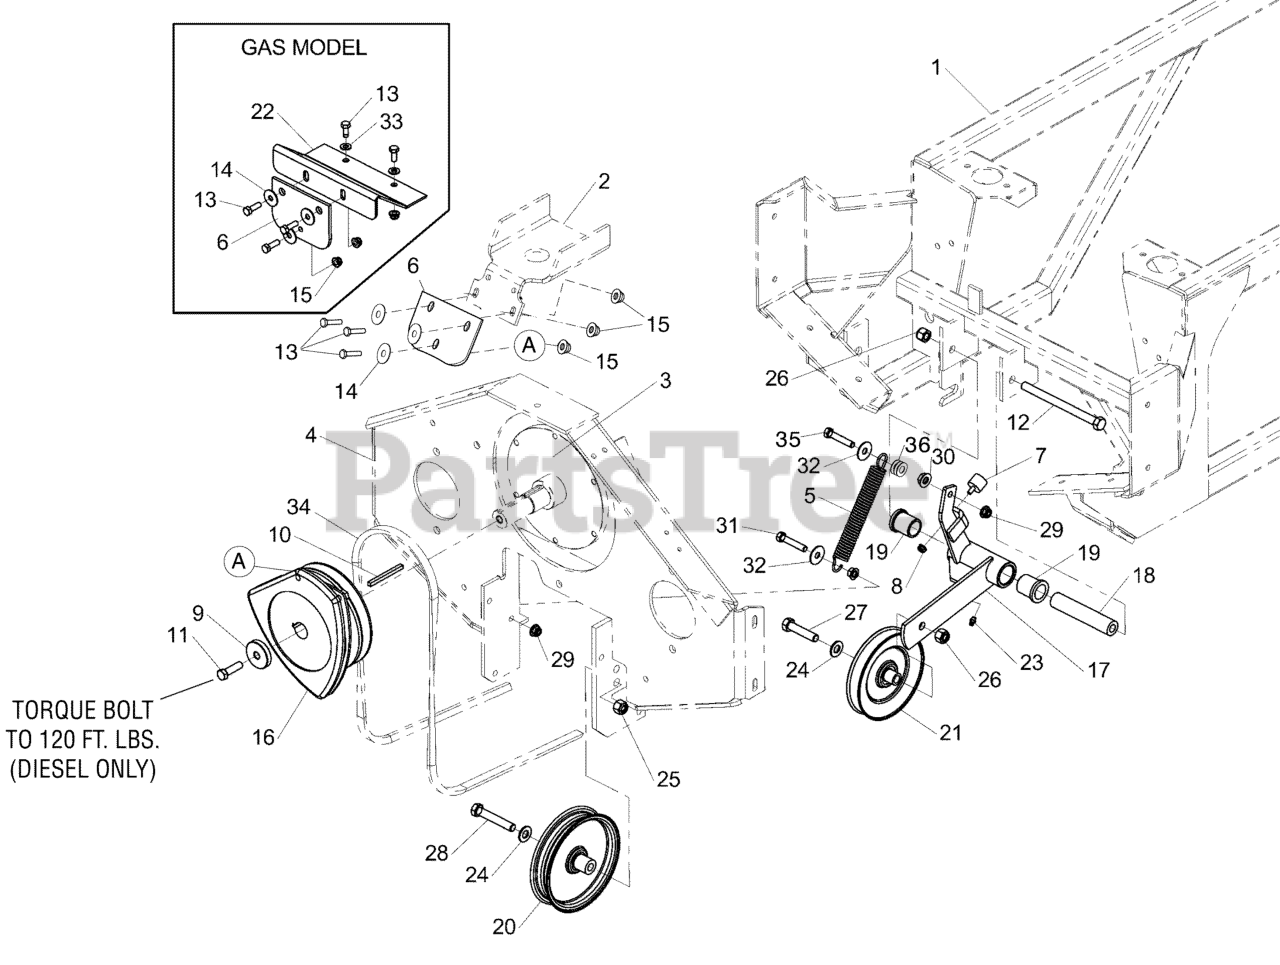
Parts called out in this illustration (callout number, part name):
1	MAIN FRAME
2	REAR ISO MOUNT
3	CRANK SHAFT / STUB SHAFT
4	PUMP PLATE
5	SPRING, EXTENSION, SWIVEL
6	CLUTCH ANCHOR PAD
7	RUBBER BUMPER 1/4-20
8	NUT, 1/4-20 HEX NYLON FLANGE
9	SPACER, .515 X 1.875 X .375
10	KEY, 1/4 SQ X 1
10	KEY, 1/4" SQ. X 3"
11	BOLT, CRANKSHAFT, 1/2-20 X 1-3/4
11	BOLT, CRANKSHAFT, 7/16-20 X 3, GD8
11	CRANKSHAFT BOLT, 7/16" X 4"
12	BOLT, 1/2-13 X 6-1/2" GD8 YZ
13	BOLT, 5/16-18 X 1" GD5 YZ
14	WASHER, .34 X 1.25 X 10 GA
15	NUT, 5/16-18 HEX NYLOCK FLANGE
16	CLUTCH,#527174,OGURA GT5
16	ELECTRIC CLUTCH
17	WELD, IDLER ARM
18	SPACER, .52 X 1.00 X 5.00
19	BUSHING, FLANGE
20	PULLEY, IDLER - 6
21	PULLEY, 6" DEEP GROVE IDLER
22	CLUTCH ANCHOR BRACKET
23	GREASE FITTING1/4-28 STRAIGHT
24	WASHER, 1/2 SAE
25	NUT, 1/2-13 HEX NYLON LOCK
26	NUT, Hex Flange, Nylock, 1/2-13
27	BOLT, 1/2-13 X 2-1/4" GD5 CZ
28	BOLT, 1/2-20 X 3-1/2" GD5 YZ
29	NUT, 3/8-16 HEX NYLOCK FLANGE
30	NUT, 3/8-16 HEX SERRATED FLANGE
31	BOLT, 3/8-16 X 1-1/2" GD5 CZ
32	WASHER, 3/8" FENDER
33	WASHER, 5/16" SAE
34	BELT
35	BOLT, 3/8-16 X 1-3/4" GD5 CZ
36	WASHER, 3/8 SAE
